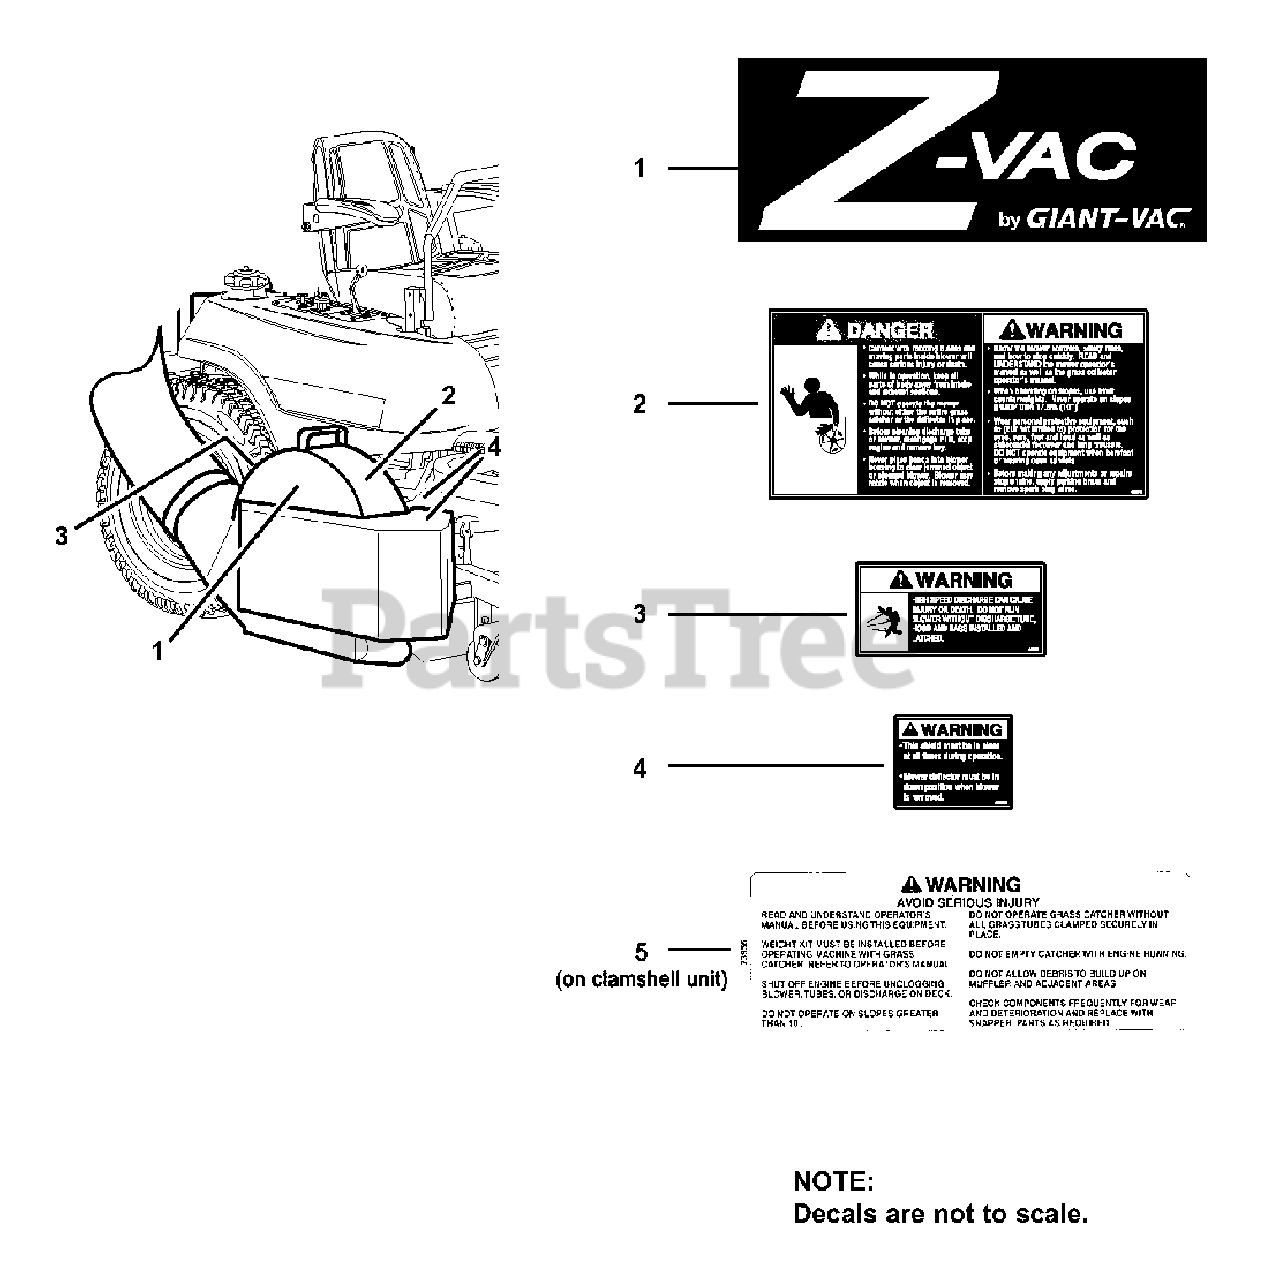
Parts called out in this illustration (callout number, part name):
1	DECAL, Z-Vac
2	DECAL, Danger, Fast-Vac
3	DECAL, Warning, Fast-Vac
4	DECAL, Warning, Fast-Vac
5	DECAL, Warning, Billboard
